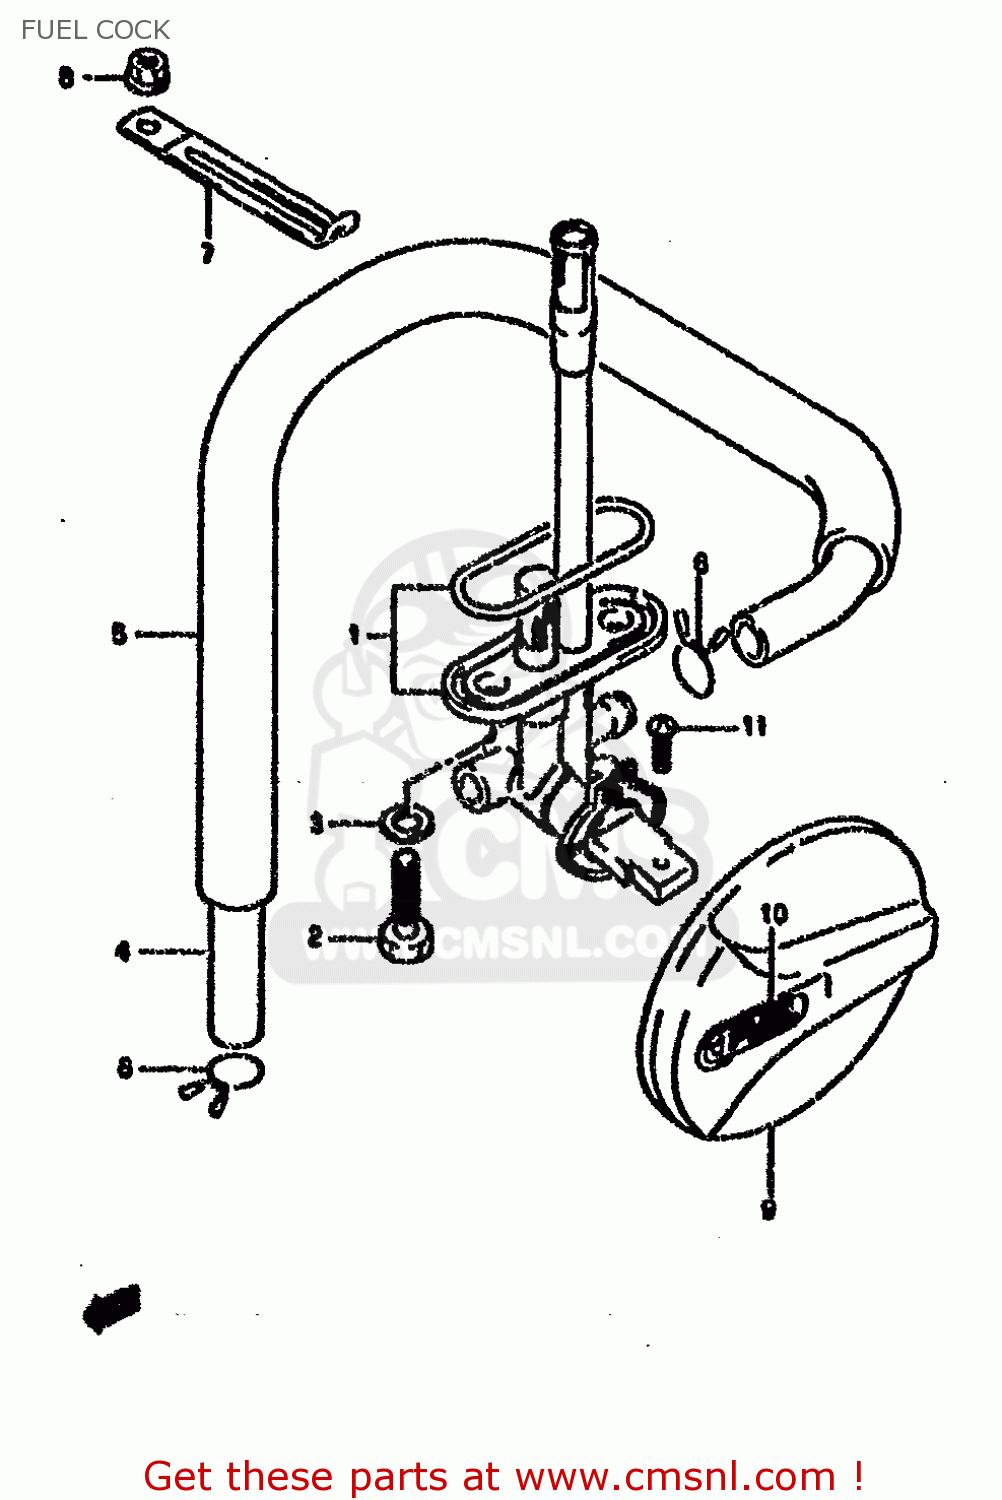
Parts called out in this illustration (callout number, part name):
1	COCK SET,FUEL
2	BOLT(6X20)
3	GASKET(6.4X11.5X0.8) (NAS)
4	HOSE(7X11X600)
5	PROTECTOR,FUEL HOSE
6	CLIP
7	CLAMP
8	NUT
9	LEVER,FUEL COCK
10	LABEL,FUEL COCK LEVER
11	SCREW
